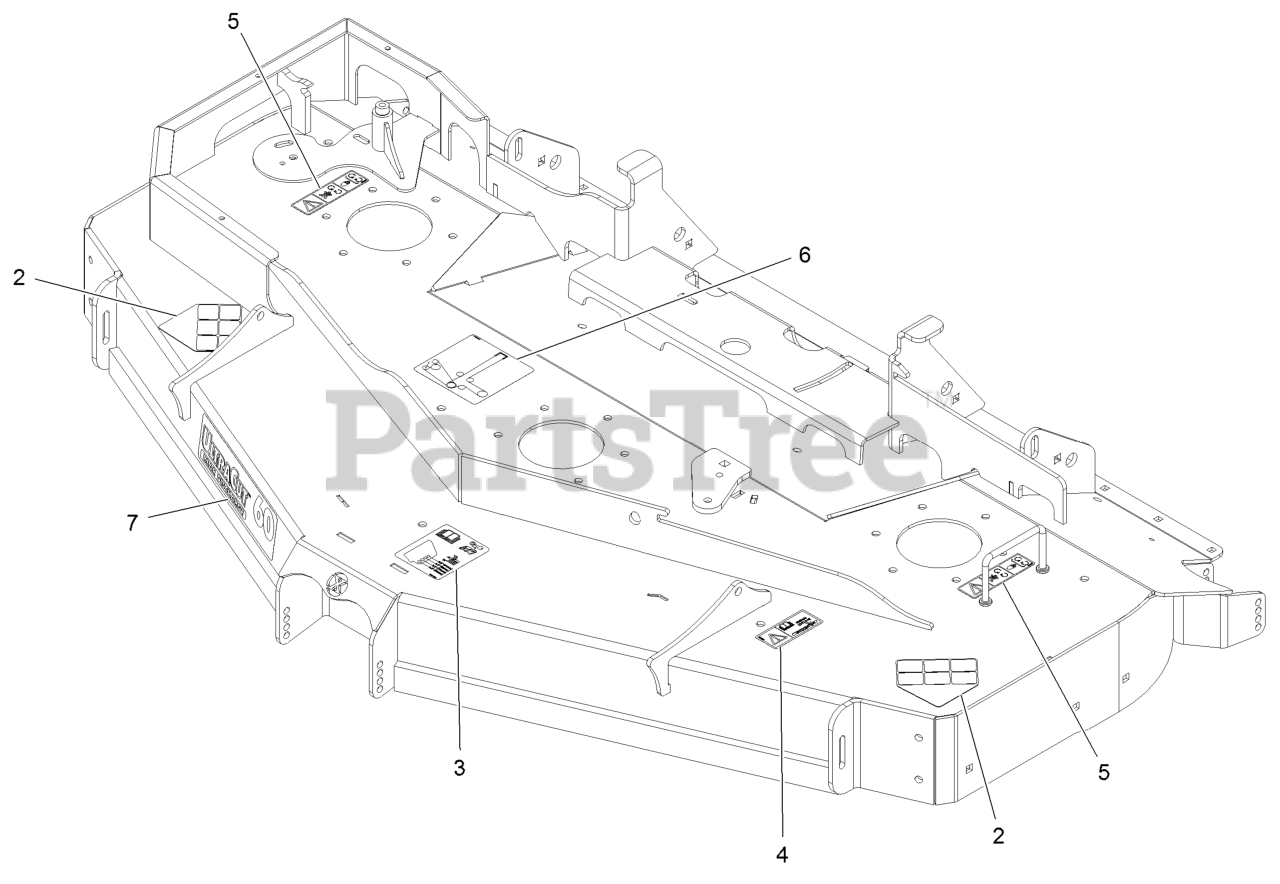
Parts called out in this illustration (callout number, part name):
2	DECAL-DANGER
3	DECAL-ROLLER, ANTI-SCALP
4	DECAL-BOLT TORQUE
5	DECAL-COVER, MISSING
6	DECAL,BELT ROUTING RD DEC
7	DECAL,REAR DISCHARGE 60
